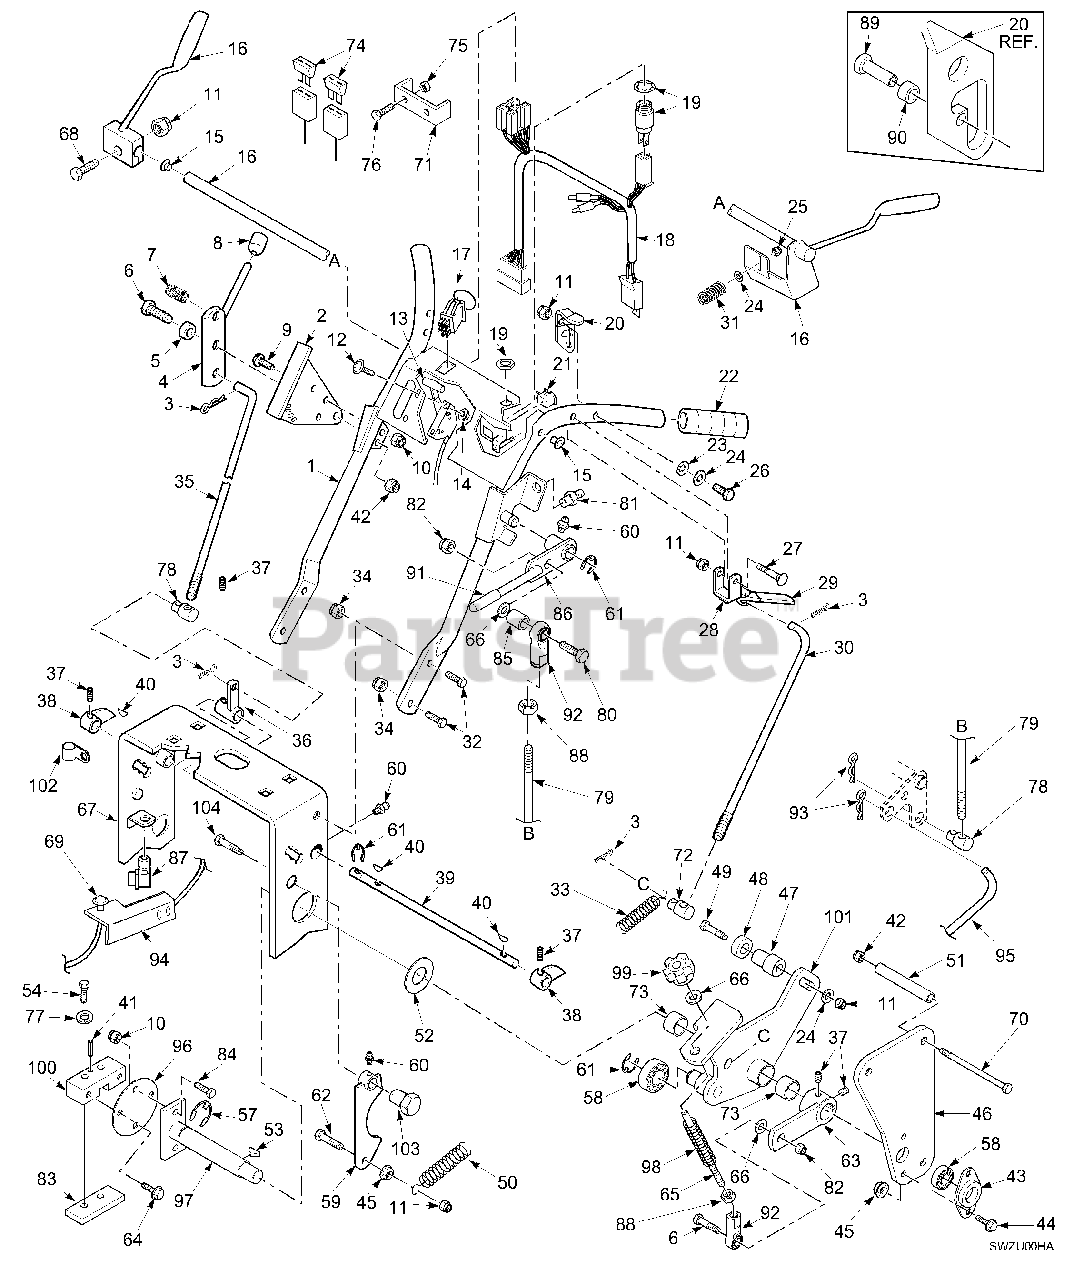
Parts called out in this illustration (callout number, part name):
1	Upper Handle Wlmt. W/Decals
2	Quadrant, Speed Control
3	Hairpin, .094 x 1.19
4	Lever, Speed Adjustment
5	Bushing, Speed Adjustment Lever
6	Hex Head Bolt, 3/8-16 x 1-1/2"
7	Ball Plunger
8	Knob, Speed Adjustment
9	Capscrew, 1/4-20 x 3/4" FHHS
10	Nut, 1/4-20 Elastic Stop
11	Nut, 5/16-18 Elastic Stop
12	Screw, #10-32 x 1/2" PW HD
13	Throttle Control
14	Nut, #10-32 Serr. Flange
15	Bushing
16	Handle, Oper. Presence-RH
17	Switch,Elec.Clutch Eng.
18	Wire Harness, Manual Start
19	Key Switch,Manual Srt.
20	Neutral Latch-RH
21	Switch, Neutral Interlock
22	Grip
23	Washer, Curved Spring
24	Flat Washer
25	Lock Washer, 1/4" Int. Tooth
26	Hex Head Bolt, 5/16-18 x 2"
27	Hex Hd. Bolt, 5/16-18 x 2-1/2"
28	Lever, Steering Control
29	Grip, Steering Control
30	Rod, Steering Control
31	Spring, Handle Return
32	Capscr., 3/8-16 x 1" Ser. Flange
33	Spring, Traction Control
34	Nut, 3/8-16 Serr. Flange
35	Rod Speed Control
36	Bellcrank, Speed Control
37	Setscrew, 1/4-28 x 1/4"
38	Cam, Speed Control
39	Jackshaft, Speed Control
40	Key, 1/8 x 1/2" Woodruff
41	Nut, 3/8-16 Elastic Stop
42	Pivot, Pump Ctrl.
43	Bushing, 1/2" ID
44	Capscrew, 5/16-18 x 1" Serr. Flg.
45	Nut, 5/16-18 Serrated Flange
46	Bar, Speed Control
47	Spacer, Speed Ctrl. Bearing
48	Bearing, Speed Ctrl. Bellcrank
49	Hex Head Bolt, 5/16-18 x 1-3/4"
50	Spring, Return
51	Knob, 5/16-18
52	Bushing
53	Handle, Neutral Adj
54	Drive Pin, 5/32 x 7/8 Type U
57	Nut, 5/16-18 Serr. Flange
58	Bearing, Ball Neutral Return
59	Cam, Neutral
60	Grease Fitting, 1/4-28 UNF
61	Retaining Ring, 5/8 Ext. "E"
62	Hex Head Bolt, 5/16-18 x 1"
63	Lever, Speed Control
64	Bellcrank, Pump Control-LH
65	Retaining Ring, 1/2 Ext. "E"
66	Flat Washer, 15/16 x 25/64 x 12 ga
67	Deck, Engine
68	Hex Head Bolt, 5/16-18 x 1-1/4"
69	Choke Control
70	Spring, Return
71	Fuse Holder
72	Swivel Joint, Steering Rod
73	Flat Washer (.344 x .688 x .065)
74	Blade Fuse, 20A
75	Nut, #10-32 Elastic Stop
76	Screw, #10-32 x 1-1/2" Phillips
77	Pin, Neutral Lock
78	Swivel Joint
79	Rod, Brake Lever
80	Hex Hd. Bolt, 3/8-16 x 1 3/4
81	Soc. Hd. Capscrew, #8-32 x 1/2
82	Nut, 3/8-16 Elastic Stop
83	Washer #8-.170 x .375 x .032
84	Retaining Ring, 5/8 Ext, "E"
85	Spacer
86	Parking Brake Lever with Grip
87	Switch, Parking Brake
88	Nut, 3/8-24
89	Bushing, bearing Retainer
90	Bearing, Neutral Lock
91	Grip, Parking Brake
92	Ball Joint, RH Thread
93	Hairpin, .094 x 1.62
94	Bracket, Choke Mtg.
95	Rod, Lower Brake
96	Plate, Coupler
97	Shaft, Pump Control
98	Spring
99	Knob, Tracking Adjustment
100	Block, Pump Control
101	Control, LH
102	Wire Loom
103	Bushing
104	Bolt, Hex Head 3/8-16 x 1-1/2"
